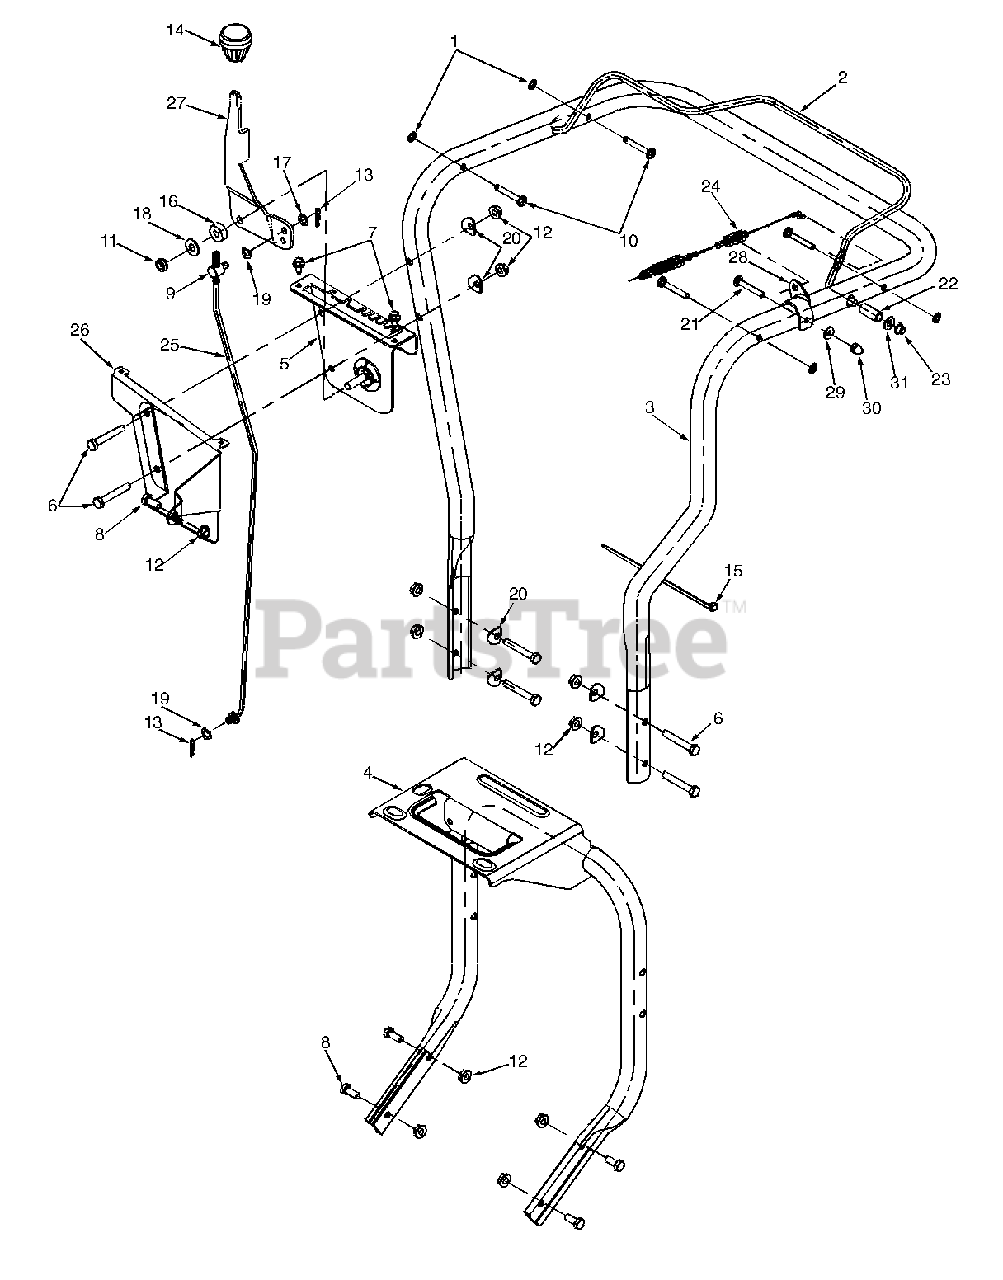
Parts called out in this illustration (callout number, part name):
1	Nut, Push, .25
2	Control Assembly, Clutch
3	Handle Assembly, Upper
4	Handle Assembly, Lower
5	Bracket Assembly, Shift
6	Screw, Hex Cap, 5/16-18 x 2.0
7	Screw,Hex Wash Hd, 4-14 x
8	Screw, Hex Cap 5/16-18 x .75
9	Ferrule
10	Pin, Stud, .250 x 1.75
11	Nut, Hex Insert Jam Lock 3/8
12	Nut, Hex Flange Lock 5/16-18
13	Pin, Internal Cotter
14	Knob, Shift
15	Cable Tie
16	Rubber Washer
17	Washer, Flat .385 x .62 x .6
18	Washer, Flat, .406 x .875 x .059
19	Washer, Spring, .390 x .62
20	Washer, Saddle, .320 x .93
21	Carr. Bolt 1/4-20 x 1.75" Lg.
23	Nut, Cap Speed
24	Cable, Clutch
25	Rod, Shift
30	Nut, Lock, Acorn 1/4-20
31	Washer, Flat 5/16
